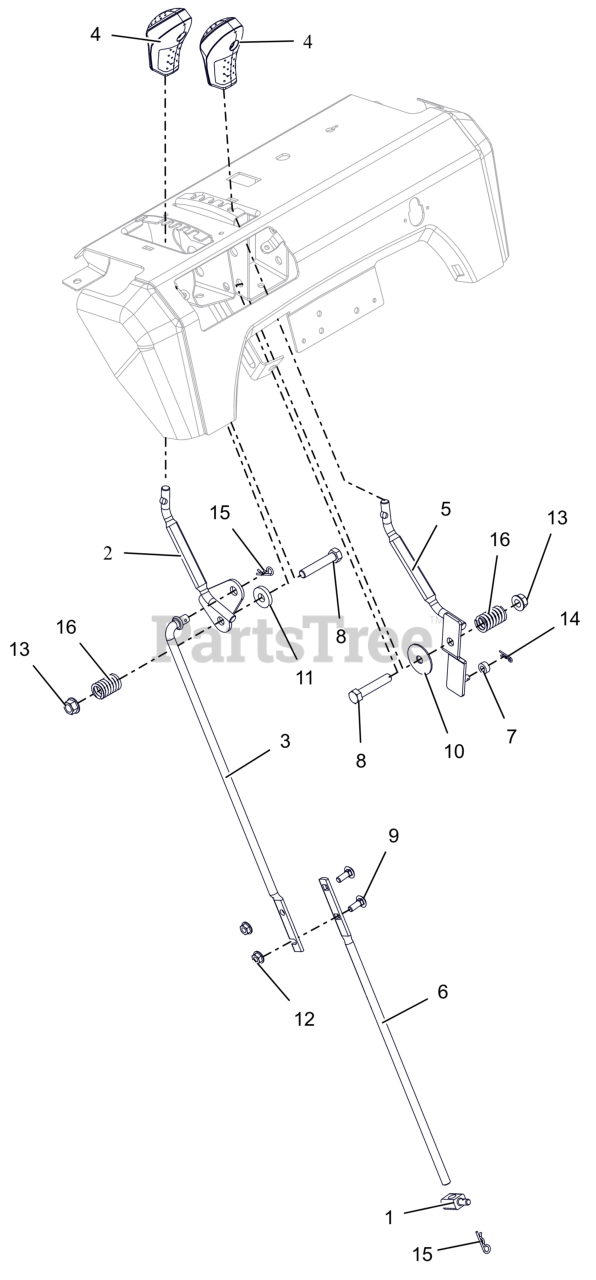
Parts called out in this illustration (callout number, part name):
1	PIVOT,SHIFT ROD .375-16(TRUNN)
2	WELDMENT,LG DASH SPEED CONTROL
3	ROD, SHIFT - UPPER
4	KNOB, CONTROL, DASH
5	WELDMENT,LG DASH DEFL CONTROL
6	ROD, SHIFT-LOWER (LG DASH DLX)
7	BSHG-SLV .265X.500X.219
8	BLT,HEX .38-16X2.00 G5 ZCC
9	BLT, RHSN .25-20X.750 G5 ZCC
10	WSHR,FLT .380X1.50X.062 ZCC
11	WSHR, FLT .406X1.00X.188 ZCC
12	NUT-LK-CTR-FLG .25-20 ZC120
13	NUT-LK-TOP-FLG .38-16 ZC120
14	PIN, HAIR #178 .06X.77 ZCC
15	PIN, HAIR #213 .08X1.19 ZCC
16	SG-COMP .125X.781X1.250
